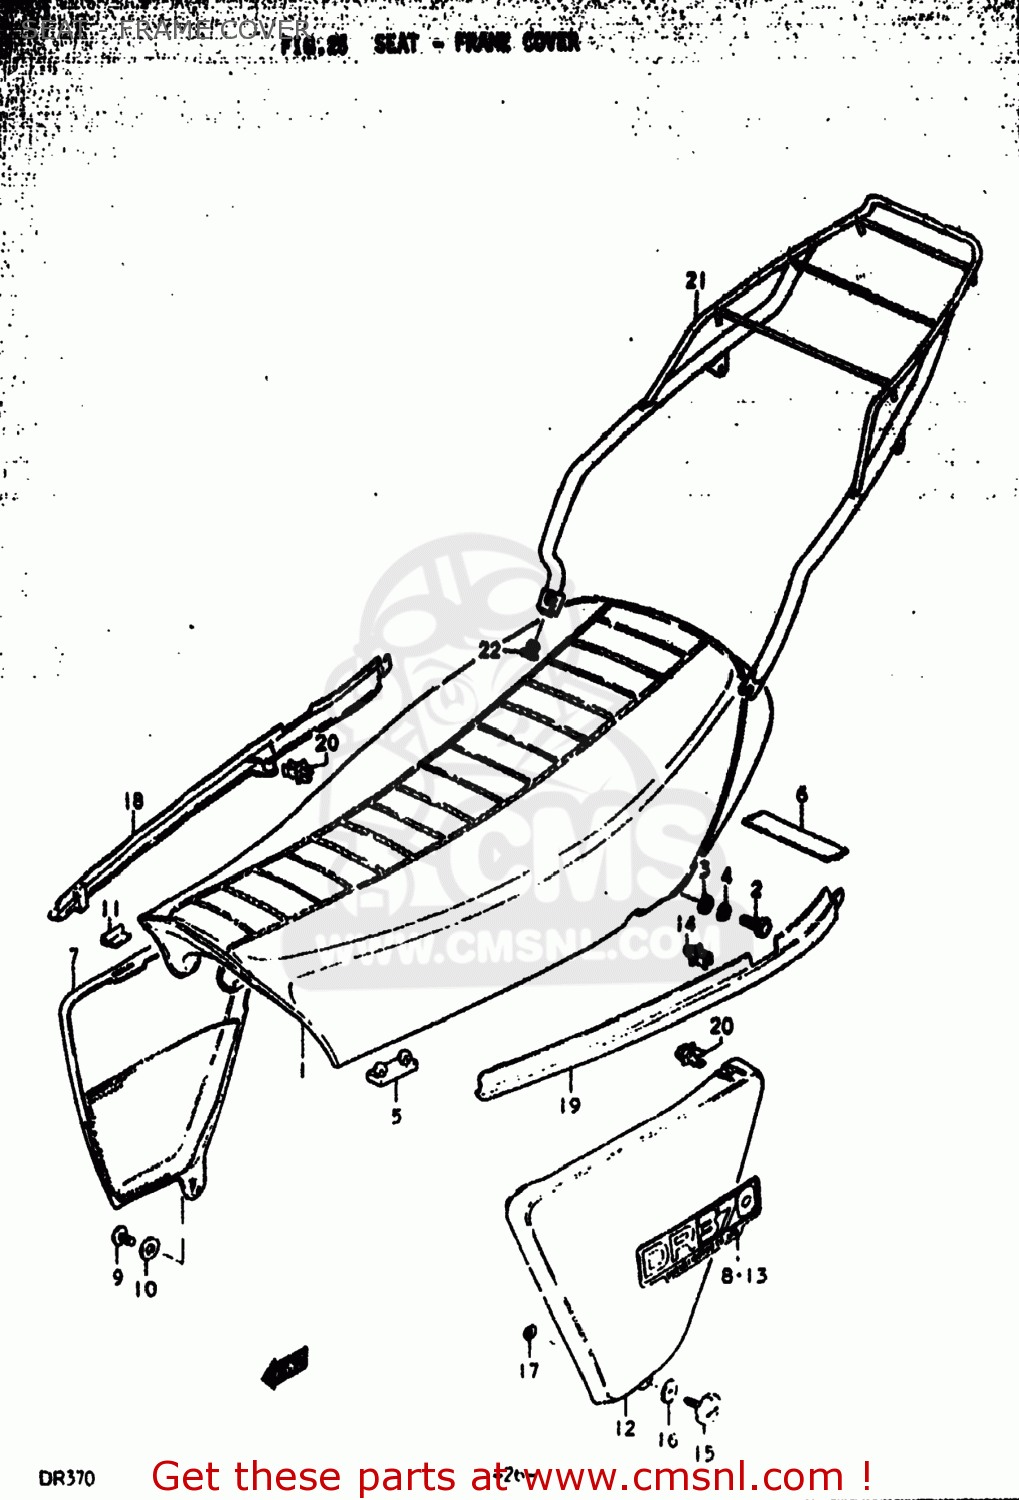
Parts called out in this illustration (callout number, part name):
1	SEAT ASSEMBLY
2	BOLT
3	WASHER
4	LOCK WASHER
5	CUSHION
6	CUSHION,FRAME
7	COVER,FRAME,RIGHT
8	EMBLEM
9	SCREW
10	WASHER
11	CUSHION,FRAME COVER
12	COVER,FRAME,LEFT
13	EMBLEM
14	CLAMP
15	KNOB,FRAME COVER,R
16	WASHER
17	NUT
18	COVER,FRAME
19	COVER,SEAT,LOWER,LEFT
20	CLAMP
21	CARRIER
22	CAP(OD:17)
